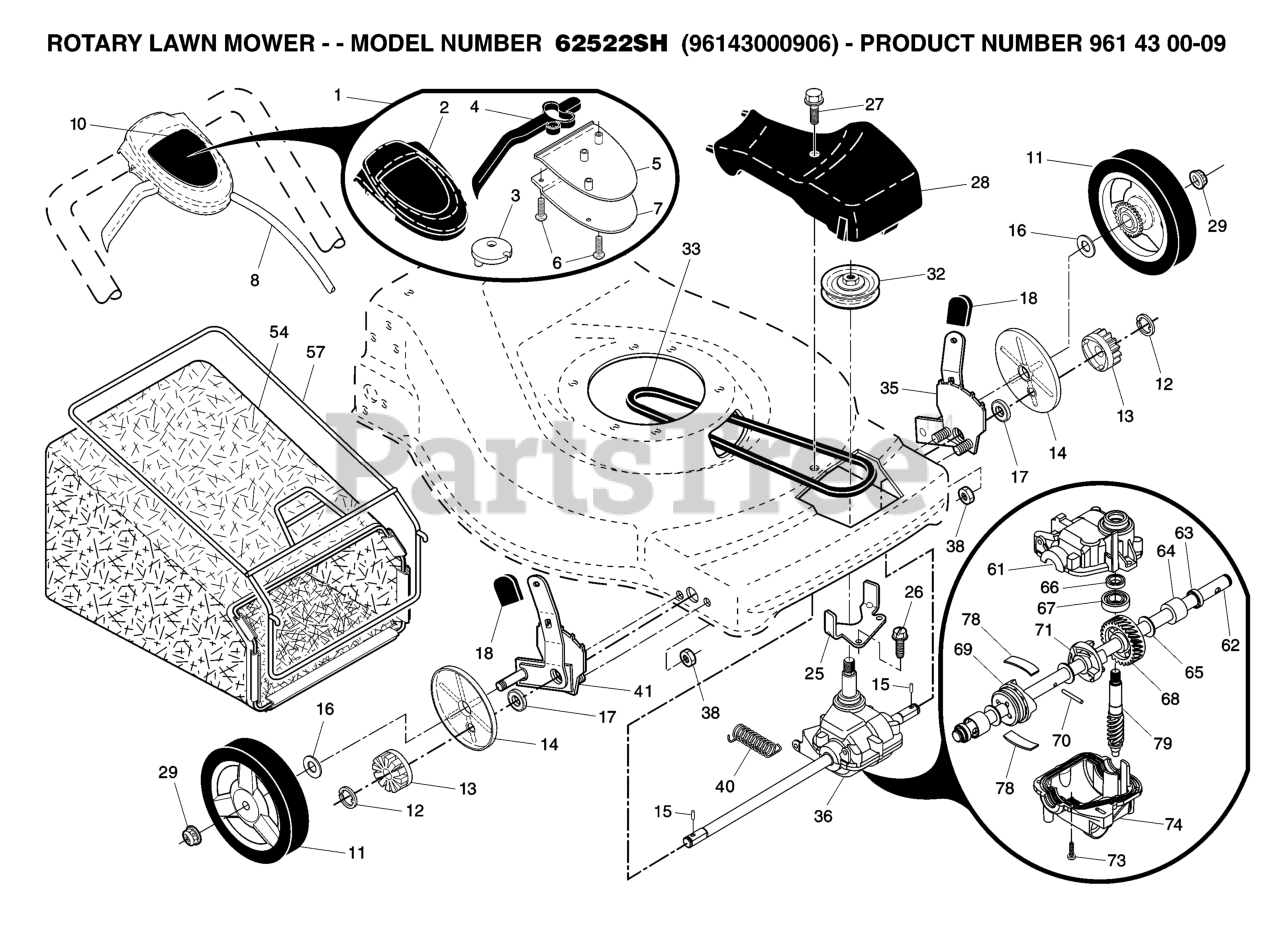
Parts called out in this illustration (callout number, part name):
1	DRIVE CONTROL ASSEMBLY (INCLUD
2	COVER TOP AUTO WALK CONTROL
3	PULLEY
4	LEVER, AUTOWALK DRIVE CONTROL
5	COVER BOTTOM AUTO WLK CONTROL
6	SCREW, PHILLIPS HEAD 10 X 5/8
7	BRACKET.DRIVE.CONTROL.MOUNT.BL
8	CABLE ASSEMBLY, DRIVE
10	DECAL, DRIVE
11	WHEEL.8X1.75.H3SPK.RAD3.GY.BU3
12	E-RING 7/16 RE
13	PINION.14.TEETH.FGD
14	COVER.DUST.WHEEL
15	PAWL.DRIVE
16	WASHER FLUT
17	BEARING ASM
18	KNOB.DELUXE.GRAY
25	BELT KEEPER
27	SCREW, HEX HD TAPPING #10-24 1
28	RP DRIVE COVER
29	NUT.HEX.FLANGE.3/8-16.LO(3 2)
32	RP PULLEY.DRIVE.EZ
33	BELT.DRIVE.FG
35	WHEEL ADJ KIT LH
36	TRANSMISSION.22.VS.FWGD
38	LOCKNUT.NYLOC.1/4-20
41	WHEEL ADJ KIT RH
54	GBAG.8471024T.SIL.HUSQ.BLU
57	FRAME GRASSBAG
61	CASE.UPPER.00254(SERVICE)
62	Shaft, Output
63	SEAL.OUTPUT.SHAFT
66	SEAL INPUT SHAFT
68	GEAR 28 TEETH 36208
69	FIXED DOG CLUTCH
70	PIN.3.50.33733
71	MOVEABLE DOG CLUTCH
74	CASE.BOTTOM.
78	SPRING LEAF
79	SHAFT WORM
